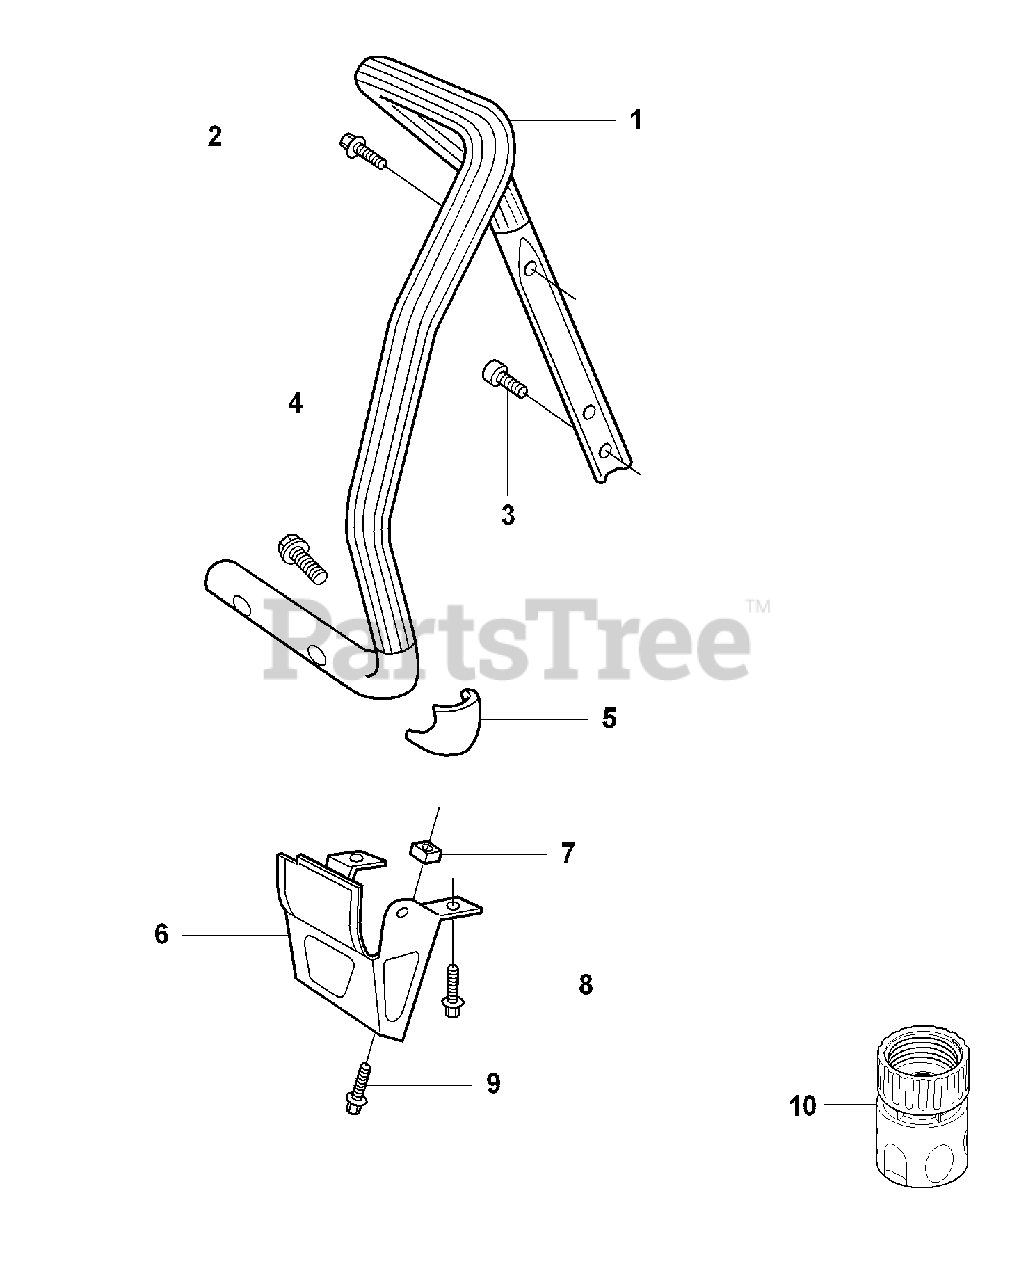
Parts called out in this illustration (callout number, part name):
2	SCREW
6	GROUND SUPPORT
10	COUPLER
